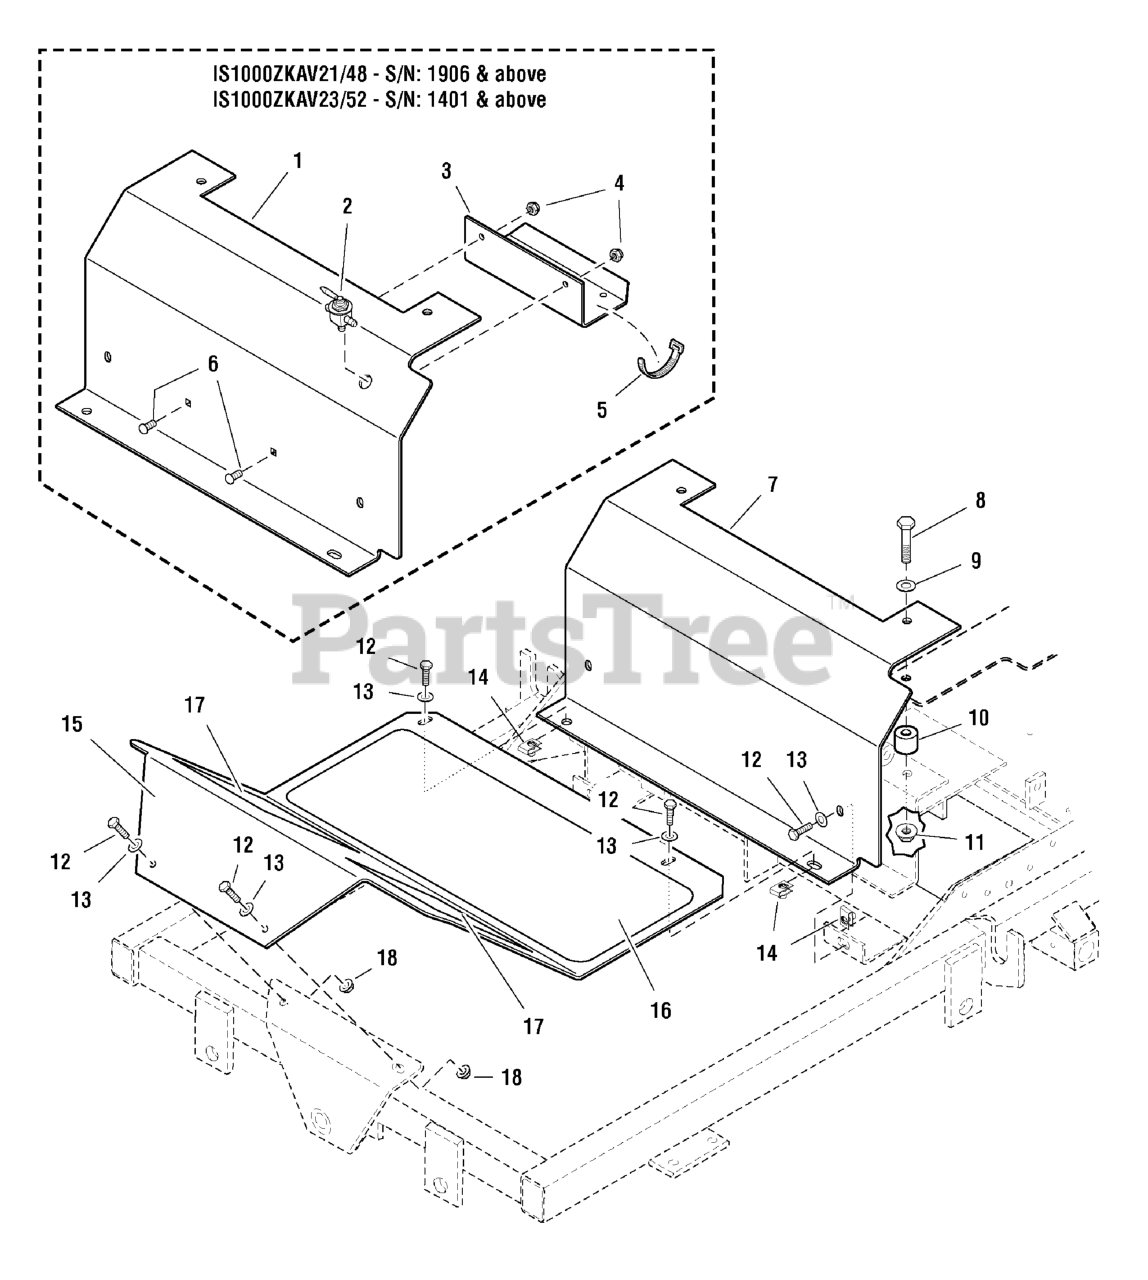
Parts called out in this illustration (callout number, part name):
1	BRAKE COVER PANEL ASSEMBLY
2	VALVE, Fuel Shut Off
3	FUEL LINE GUIDE
4	NUT, 1/4-20 HEX NYLON LOCK
5	TIE WRAP, 11"
6	BOLT,1/4-20X0.750,GR5,STD NECK,SQ,ZC/CL
7	BRAKE COVER PANEL
8	BOLT, 3/8-16 X 2, GD5, CZ
9	WASHER, 3/8 SAE
10	SPACER, .39 x 1.00 x .88
11	NUT, 3/8-16 Hex Serrated Flange
12	BOLT, 5/16-18 X 1 GD5 YZ
13	WASHER, 5/16" SAE
14	BODY CLIP, 5/16-18-7GA MATERIAL
15	FLOOR PLATE
16	SAFETY WALK
17	SAFETY WALK
18	NUT, 5/16-18 HEX SERRATED FLANGE (SMALL)
